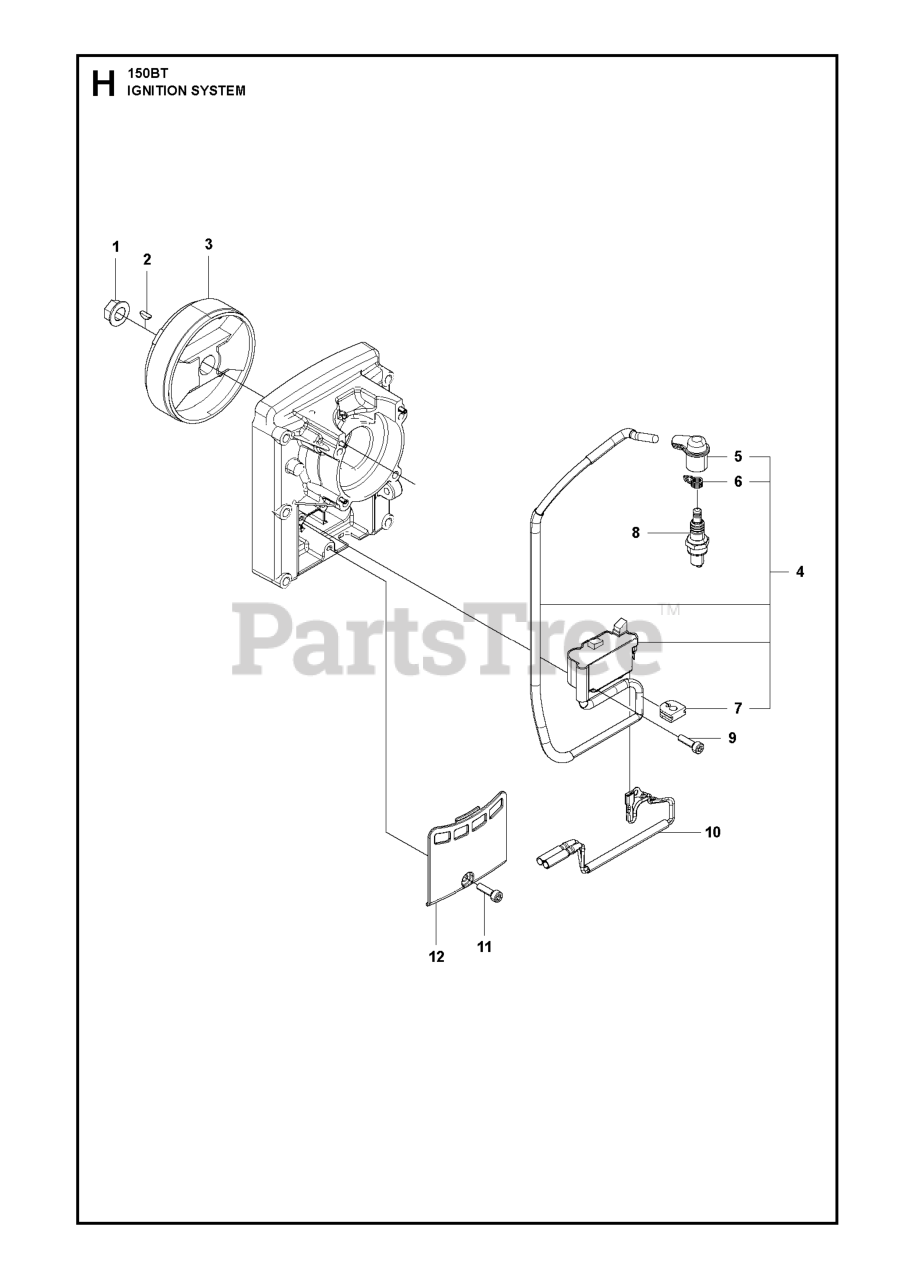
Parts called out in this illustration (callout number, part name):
1	NUT
1	Nuts
3	FLYWHEEL
4	IGNITION COIL
4	COIL ASSY
6	SPRING
7	GROMMET
8	SPARK PLUG TORCH AC7R
8	SPARK PLUG NGK CMR7H
